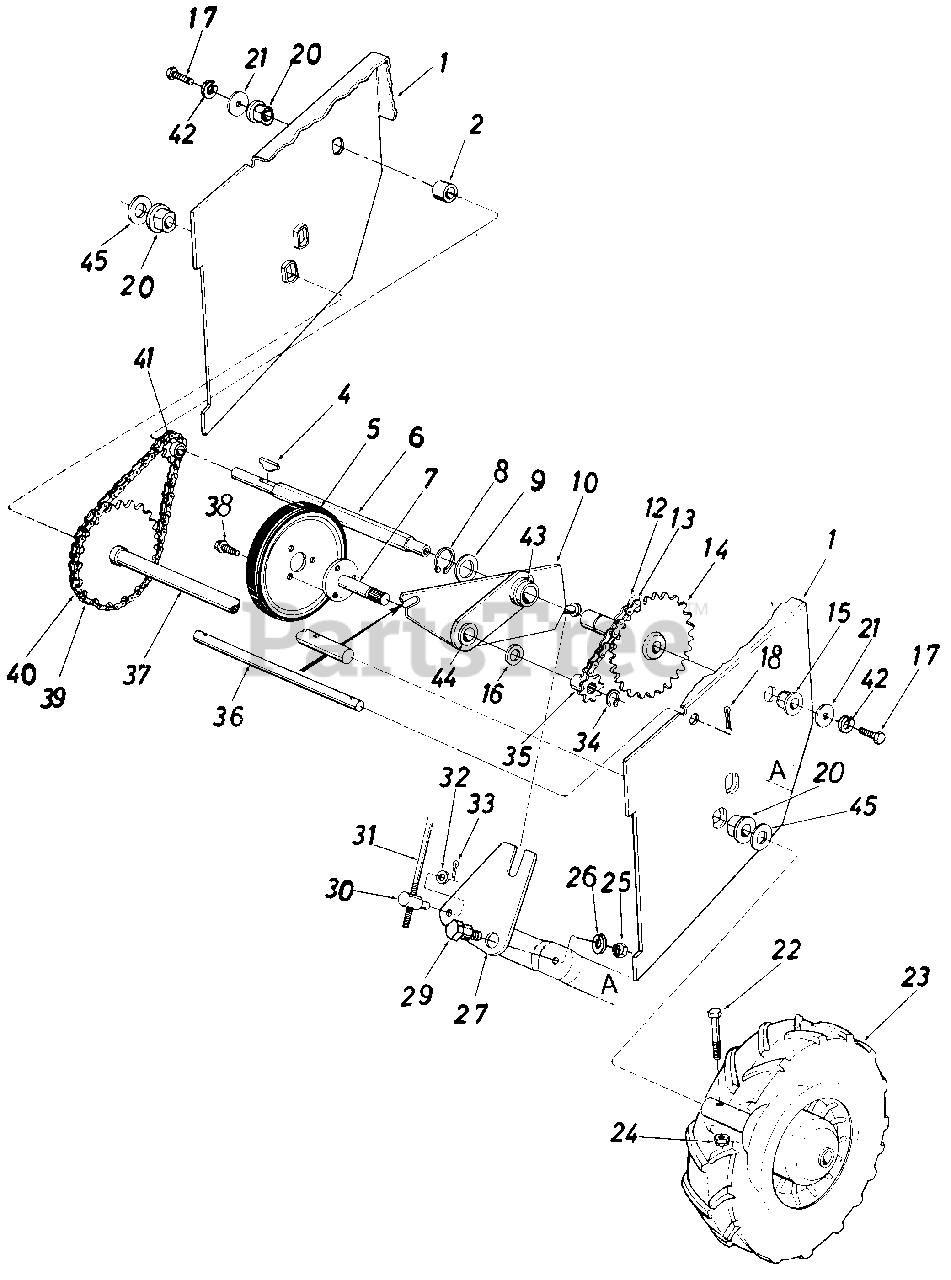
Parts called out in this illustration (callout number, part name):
1	Frame Ass'y.
2	Spacer .50" I.D. x .75" O.D. x .78" Lg.
4	#4 Hi-Pro Key 3/32 x 5/8" Dia.
5	Friction Wheel Ass'y.
6	Hex Shaft
7	Friction Wheel Mounting Plate Ass'y.
8	Snap Ring 1.00" Dia. Shaft
9	Fl-Wash. 1.00" x 1.63" O.D. x .03
10	Sliding Bracket Ass'y.
12	#41 Chain 1/2" Pitch x 35 Links
13	Master Link for #41 Chain
14	32 Teeth Sprocket Ass'y.
15	Hex Flange Brg. .630" I.D.
16	Fl-Wash. .62" I.D. x 1.00" O.D. x .06
17	Hex Lock Bolt 5/16-18 x .62" Lg.
18	Cotter Pin 3/32" Dia. x .75" Lg.
20	Flange Brg, w/Flats .755" I.D.
21	Fl-Wash. .34" I.D. x 1.12" O.D. x .125
22	Hex Bolt 5/16-24 x 1.50" Lg.
23	Wheel Ass'y. Comp. - L.H.12.5 x 35
24	Hex Ins. Jam L-Nut 5/16-24 Thd
25	Hex Jam Nut 3/8-16 Thd.
26	L-Wash. 3/8" I.D.
27	Shifting Linkage Bracket
29	Shld. Bolt .625" Dia. x .170" Lg.
30	Adjustment Ferrule
31	Shifting Rod 5/16" Dia. x 32.50" Lg.
32	Fl-Wash. .34" I.D. x .64" O.D. x .06
33	Cotter Pin 3/32" Dia. x .75" Lg.
34	Snap Ring .562" Dia. Shaft
35	Sprocket 7 Teeth x .50" Pitch
36	Shaft .50" Dia. x 9.50" Lg.
37	32 Teeth Wheel Axle Ass'y.
38	Hex Wash. Hd. Self-Tap Scr. 5/16-24 x .50" Lg.
39	#420 Chain 1/2" Pitch x 39 Links
40	Master Link for #420 Chain
41	8 Teeth Center Sprocket
42	L-Wash. 5/16" I.D.
43	Plastic Bearing
44	Bronze Bearing
45	Fl-Wash. .76" I.D. x 1.49 O.D.
